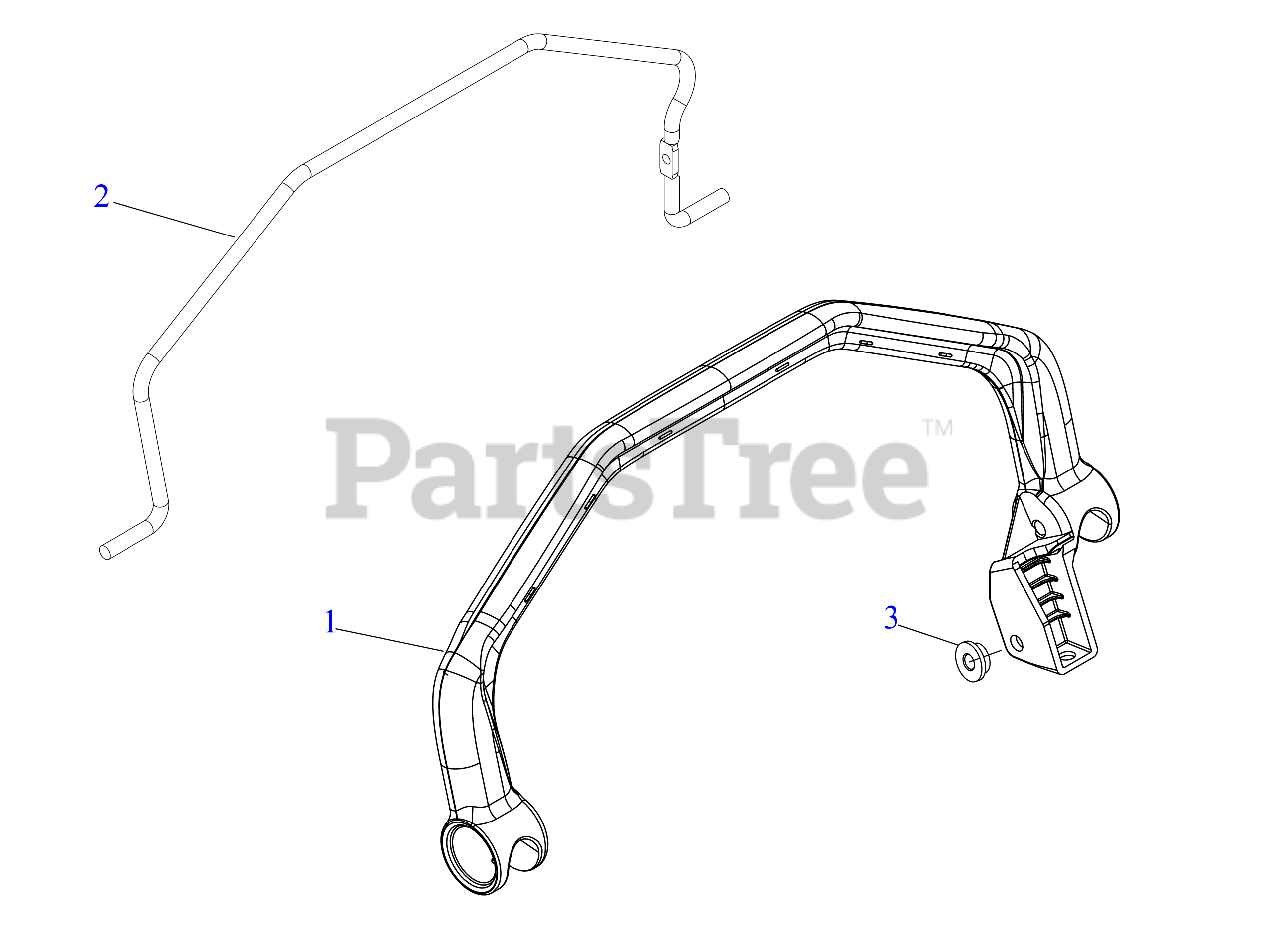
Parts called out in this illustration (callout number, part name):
1	DRIVE HANDLE (SBD GRAY)
2	OPERATOR BAIL (LIBERTY RED)
3	SHOULDER SPACER
